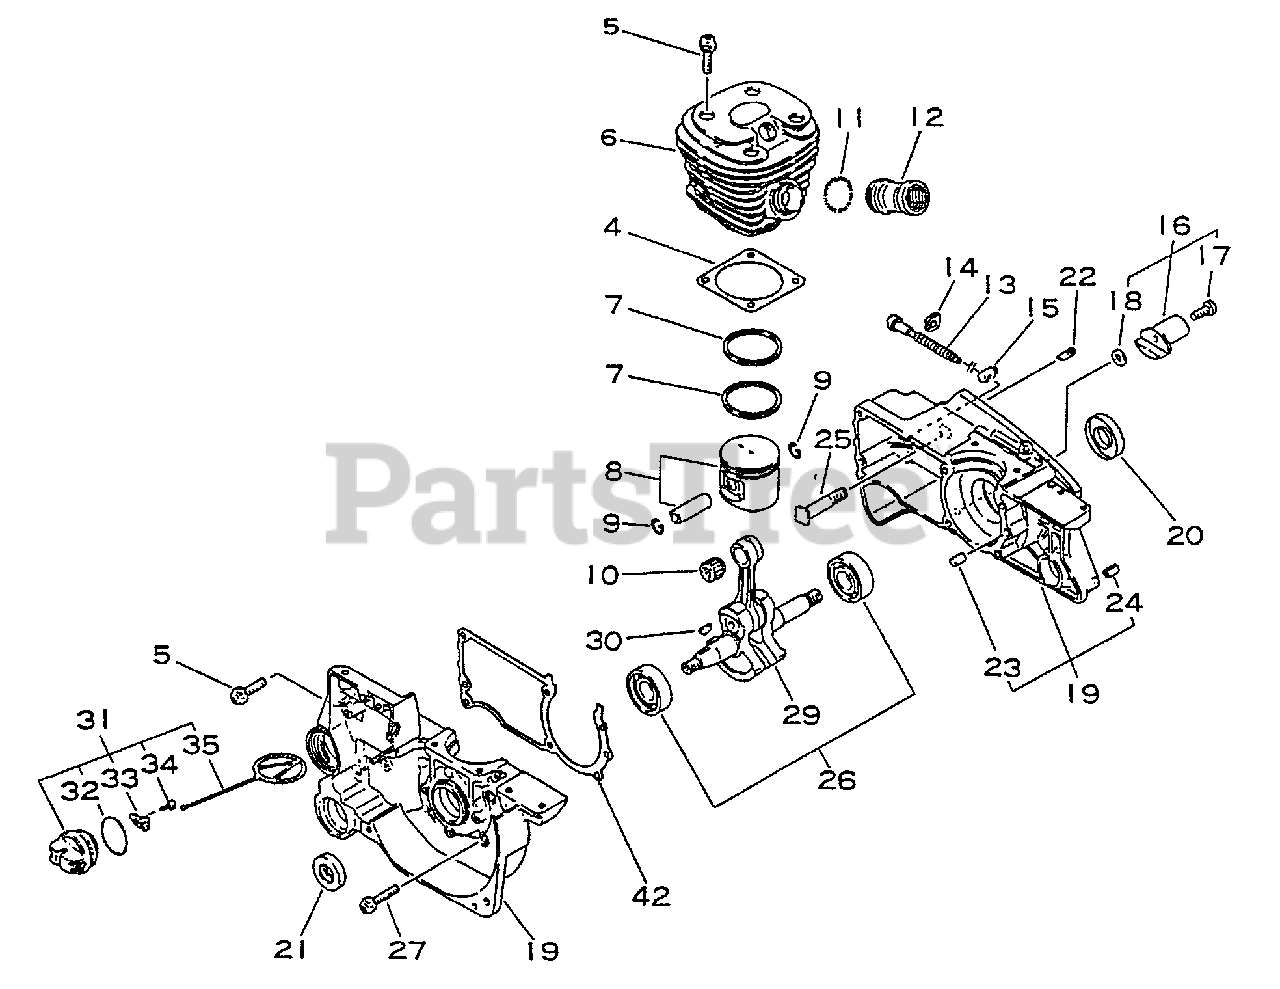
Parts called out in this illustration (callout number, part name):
4	GASKET, CYLINDER
5	SCREW - 5X20
6	CYLINDER
7	RING, PISTON
8	PISTON KIT
9	RING, RETAINING - 8
10	BEARING, NEEDLE
11	BAND
12	ADAPTOR, INTAKE
13	SCREW, TENSIONER
15	TENSIONER, CHAIN
16	CHAIN CATCHER KIT
17	SCREW - 5X20
18	WASHER - 5
19	CRANKCASE KIT
20	SEAL, OIL
21	SEAL, OIL
22	VENT, TANK
23	PIN - LOCATING
24	PIN - SPRING -- 5X10
25	STUD, GUIDE BAR
26	BEARING SET
27	SCREW - 5X30
29	CRANKSHAFT ASSY
31	CAP ASSY
32	O-RING - 25
33	RETAINER
34	SCREW - 3X8
35	CONNECTOR, CAP
42	GASKET, CRANKCASE
